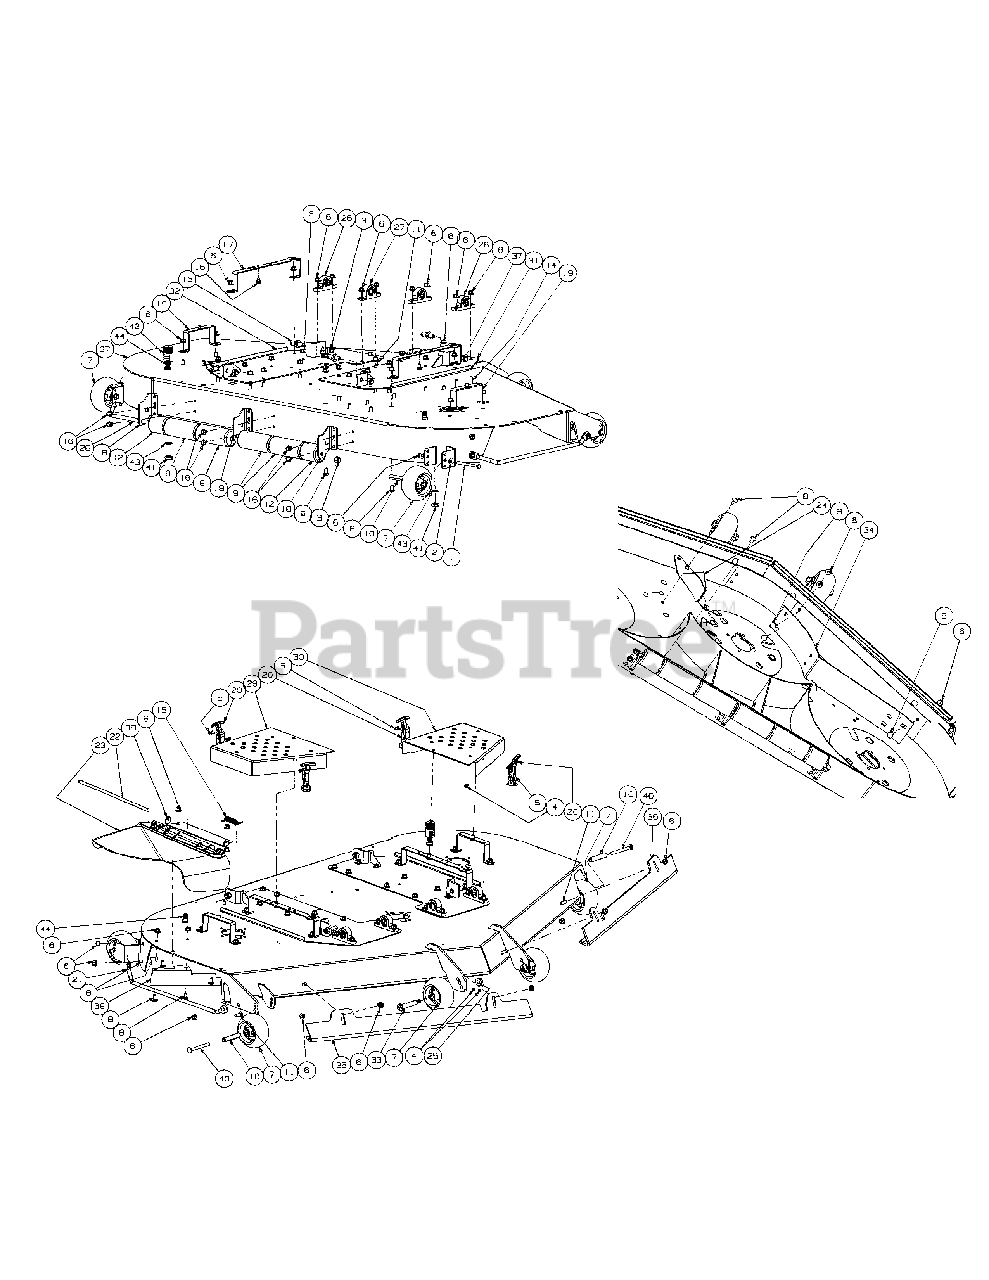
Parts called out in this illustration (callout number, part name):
1	Hex Cap Screw, 3/8-16, 4.00
2	Flat Washer, 3/8
3	Lock Nut, Nylon Insert, 1/2-13
4	Lock Nut, Nylon Insert, #10-32
5	Phillips Head Screw, #10-32 x 1/2
6	Flange Lock Hex Nut, 3/8-16
7	Complete Wheel, 5.00 Dia.
8	Carriage Bolt, 3/8-16 x .75 Lg.
9	Front Roller
10	Wheel Spacer
11	Carriage Bolt, 3/8-16 x 1
12	Grass Catcher Roller
13	Pin, 5/8 Dia. x 1.2 Lg.
14	Carriage Screw, 3/8-16 x 1.25
15	Torsion Spring, 0.4ID x 2.16Lg
16	Hex Index Washer Screw, 3/8-16, .5
17	Belt Cover Support
19	Outer Belt Cover Support Assembly
20	T-Handle Latch Draw
21	Finger Guard
22	Pin, .375 x 14.06
23	Chute Deflector
24	Discharge Baffle Weldment
25	Nut, 1/2-13, Flangelock
26	Pillow Block, Steel
27	Pillow Block, Steel
28	J-Hook w/ Threaded Roller
29	Right Hand Deck Belt Cover
30	Left Hand Deck Belt Cover
31	Right Hand Deck Lift Bracket
32	Left Hand Deck Lift Bracket
33	Shoulder Bolt, .625 x 3.00 x 3/8-16
34	Baffle, 72" Adjustment
35	Right Hand Front Adjustment Skirt
36	Left Hand Front Adjustment Skirt
40	Carriage Bolt, 3/8-16 x 4.00
41	Hex Nut, M16-1.5
42	Water Nozzle Adaptor
43	Lock Washer, 17 x 23.8 x 1.95
44	Deck Water Nozzle
